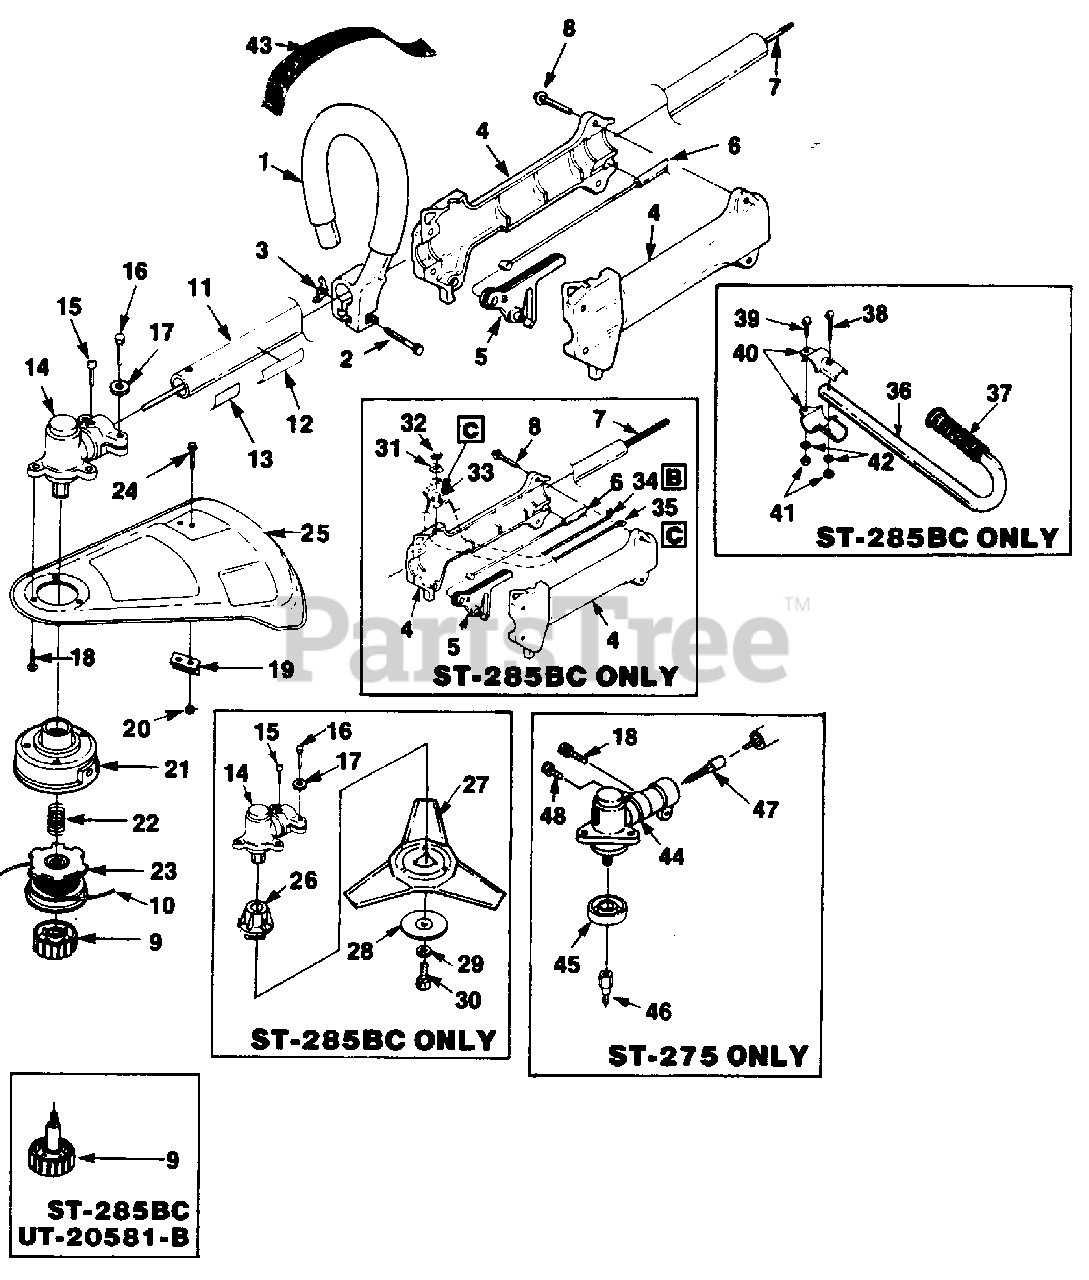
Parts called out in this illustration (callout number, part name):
1	HANDLE- Front
2	SCREW (1/4-20 x 2")
3	NUT- Wing
4	HANDLE GRIP ASSEMBLY
5	TRIGGER
6	CABLE- Throttle
7	SHAFT- Flexible (ST-285 & ST-285BC)
8	SCREW- Plastite (#8 x 3/4")
9	RETAINER- Spool (R.H.) (ST-285)
10	LINE- Replacement (.080 Dia.) (100 Ft.)
11	HOUSING- Driveshaft
12	DECAL- Starting Instructions
13	DECAL- Warning
14	GEAR HEAD ASSEMBLY (ST-285)
15	SCREW- (10-24 x 3/8")
16	SCREW- (10-24 x 1")
17	LOCKWASHER
18	SCREW- (10-24 x 3/8")
19	BLADE- Cut-off (ST-285 & ST-285BC)
20	NUT (10-24)
21	HOUSING & EYELET (Dual Line)
22	SPRING- Compression
23	SPOOL & STRING (Dual Line)
24	SCREW (10-24 x 3/8")
25	DEFLECTOR- Grass
26	ADAPTOR
27	BLADE- Weed
28	WASHER- Cupped
30	SCREW- (5/16-18 x 1")
31	PLATE- Indicating
32	NUT
33	SWITCH- Toggle
34	LEAD- Electrical
35	LEAD- Ground
36	"J" HANDLE
38	SCREW- (1/4-20 x 1 1/2")
39	SCREW- (1/4-20 x 1")
40	CLAMP- Handle bar
41	NUT- (1/4-20)
42	WASHER (1/4")
43	HARNESS w/CONNECTOR
44	GEAR HEAD ASSY. (ST-275)
45	WASHER- Flange
46	ADAPTOR- Shaft
47	ADAPTOR- Drive
48	SCREW- (1/4-20 x 7/8")
